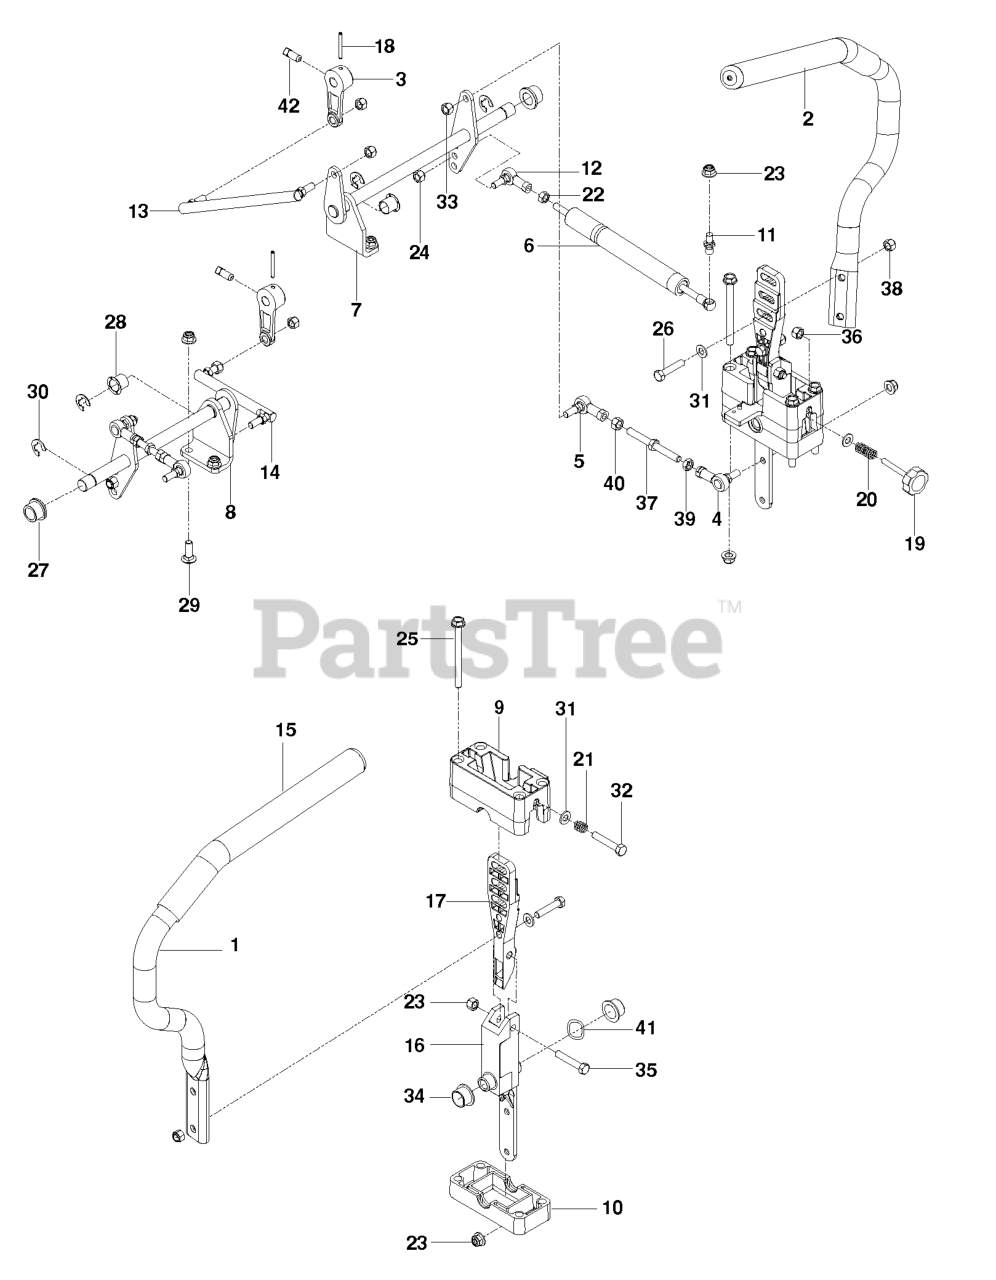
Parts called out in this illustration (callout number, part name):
1	LEVER.DRIVE.W/GRIP.RIGHT
2	LEVER.DRIVE.W/GRIP.LEFT
4	SPHERICAL ROD END, LH
5	SPHERICAL ROD END, RH
6	DAMPENER W/SPRING
7	CONTROL WLDMT, LT
8	CONTROL WLDMT, RT
9	BLOCK, UPPER
10	BLOCK, LOWER
11	STUD.BALL.10MM
13	LINK, MOTION, LT
14	LINK, MOTION, RT
15	GRIP - DRIVE LEVER 12"
16	PIVOT SECTION, DR CNTRL
17	MOUNT, DR CNTRL HANDLE
18	PIN, SPIRAL, 5/32 X 1 1/2
22	NUT M8 X 1.25 STD HEX
23	5/16-18 NYLOC FLANGE NUT
24	NUT M8 NYLOC
25	HHFS 5/16-18 X 3 3/4
26	CAPSCREW 5/16 X 1/1/2 HEX HEAD
27	BUSHING, FLANGED, 5/8
28	BUSHING, CLIP, 5/8
29	RHSNB 5/16C X 1
30	E-RING 5/8
31	FLAT WASHER 5/16 SAE
32	HCS 5/16-18X1-3/4 TPBLT
33	NUT 5/16-24 CNTRLK
34	BEARING, FLANGE
35	HCS 5/16C X 1 3/4
36	NUT 5/16C HEX
37	JACK SCREW
38	NUT 5/16 NYLOC
39	NUT 5/16F LEFTHAND
41	WASHER, .825 X 1.087, WAVE
42	SCREW 5/16C X 5/8 SQ HEAD
